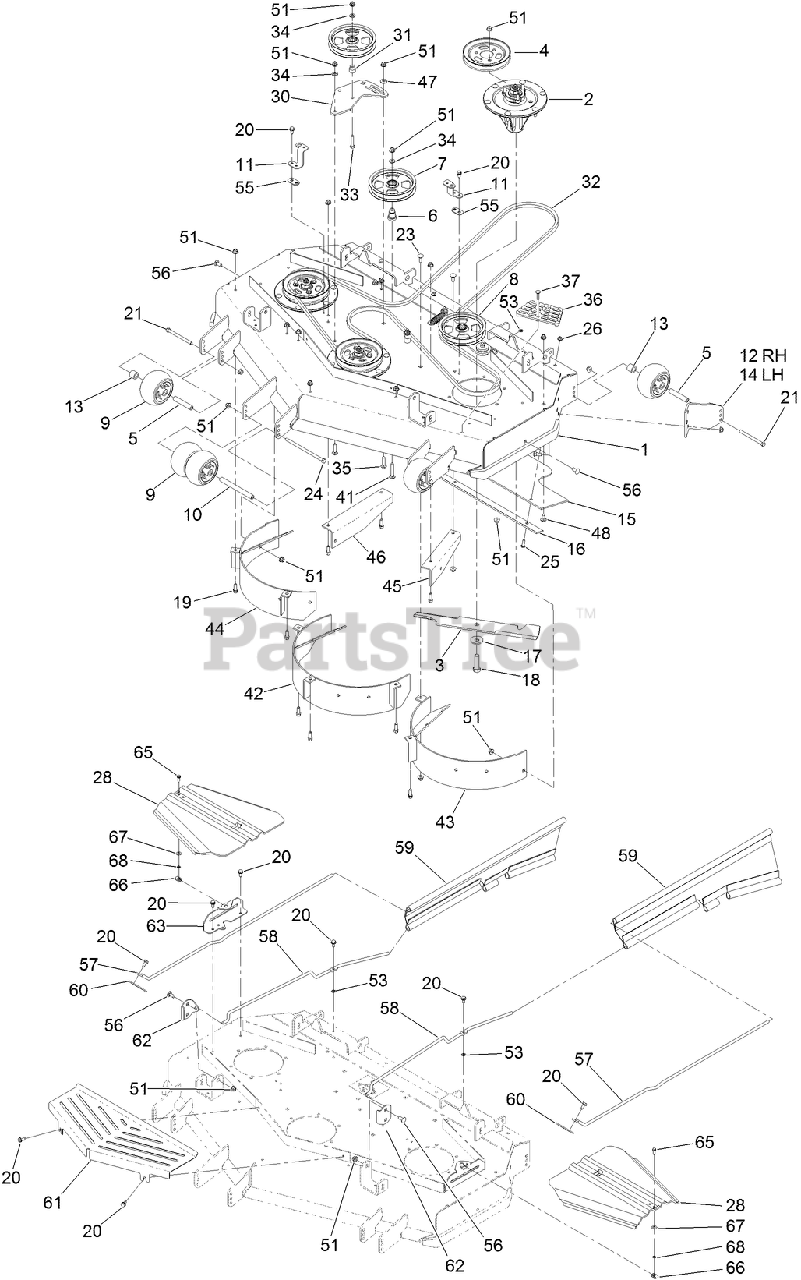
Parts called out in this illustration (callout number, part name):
1	DECK DECAL ASM
2	SPINDLE ASM
3	BLADE-18IN, HI FLOW
4	PULLEY
5	TUBE-SPANNER
6	MOUNT-PULLEY
7	PULLEY-IDLER, FLAT
8	SPRING IDLER ASM
9	ROLLER-SCALP, ANTI
10	SPACER-WHEEL
11	BRACKET-COVER, TALL
12	MOUNT-ANTI SCALP, RH
13	TUBE-SPACER
14	MOUNT-ANTI SCALP, LH
15	DEFLECTOR-RUBBER
16	SKID-SKIRT
17	WASHER-BLADE BOLT, HEAVY
18	SCREW-BLADE
20	SCREW-HWHTF
21	SCREW-HH
23	SCREW-HH
24	SCREW-HH
25	SCREW-CARR
26	NUT-HF, NI
28	COVER-BELT
30	PLATE-IDLER
31	BUSHING-IDLER
32	BELT-V
33	SCREW-HH
34	WASHER-FLAT
35	SCREW-HH
36	STEP-DECK
37	SCREW-CARR
41	SCREW-HH
42	BAFFLE-CENTER
43	BAFFLE-LH
44	BAFFLE-RH
45	BAFFLE-TRAILING
46	BAFFLE-TRAILING
47	WASHER-BELLEVILLE
48	SCREW-HH
51	NUT-HF, NI
53	NUT-PUSH
55	SPACER-BELT COVER
56	SCREW-CARR
57	ROD-SUPPORT, UPPER
58	ROD SUPPORT, LOWER
59	GUARD SIDE
60	BRACKET-MOUNTING, UPPER ROD
61	SHIELD-FRONT
62	BRACKET-MOUNTING, FRONT
63	BRACKET-SUPPORT, SPINDLE COVER
65	SCREW-HWH
67	WASHER-THRUST
68	NUT-RETAINER
